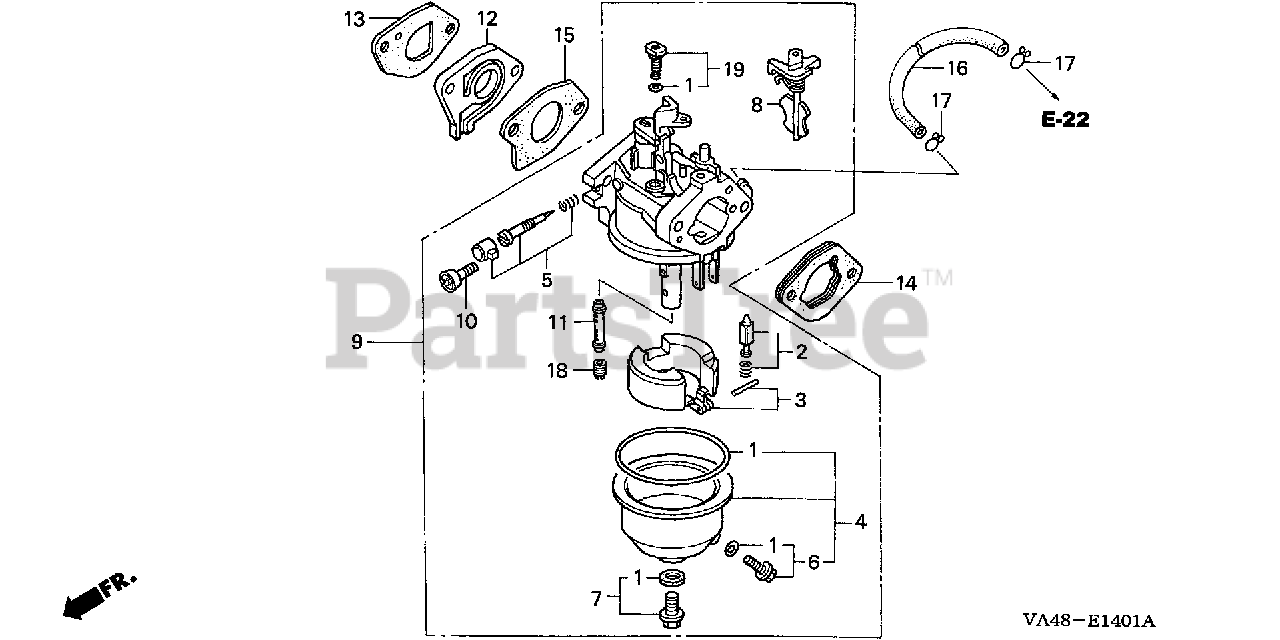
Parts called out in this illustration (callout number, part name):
1	GASKET SET (CARBURETOR NO.)
2	VALVE SET, FLOAT (CARBURETOR NO.) (SEAT NOT INCLUDED)
3	FLOAT SET
4	CHAMBER SET, FLOAT (CARBURETOR NO.)
5	SCREW SET
6	SCREW SET, DRAIN (Honda Code 1672187). (CARBURETOR NO.)
7	SCREW SET B
7	SCREW SET
8	CHOKE SET
9	CARBURETOR ASSY. (BE52B D)
10	SCREW, THROTTLE STOP
11	NOZZLE, MAIN (CARBURETOR NO.)
12	INSULATOR, CARBURETOR
13	GASKET, CARBURETOR (HPE)
14	SPACER, CARBURETOR
15	GASKET, CARBURETOR
16	TUBE, FUEL VALVE (170MM)
16	TUBE, FUEL VALVE (175MM)
16	BULK HOSE, FUEL (4.5X3000) (Honda Code 5137104). (4.5X140)
17	CLIP, TUBE (B8)
18	JET, MAIN (#50) Use from Engine SN BE52B B.
18	JET, MAIN (#52)
18	JET, MAIN (#55) (CARBURETOR NO.) Use up to Engine SN BE03A J.
19	JET SET, PILOT (#35)
20	CLIP, TUBE (B8)
20	CLIP, TUBE (B10)
